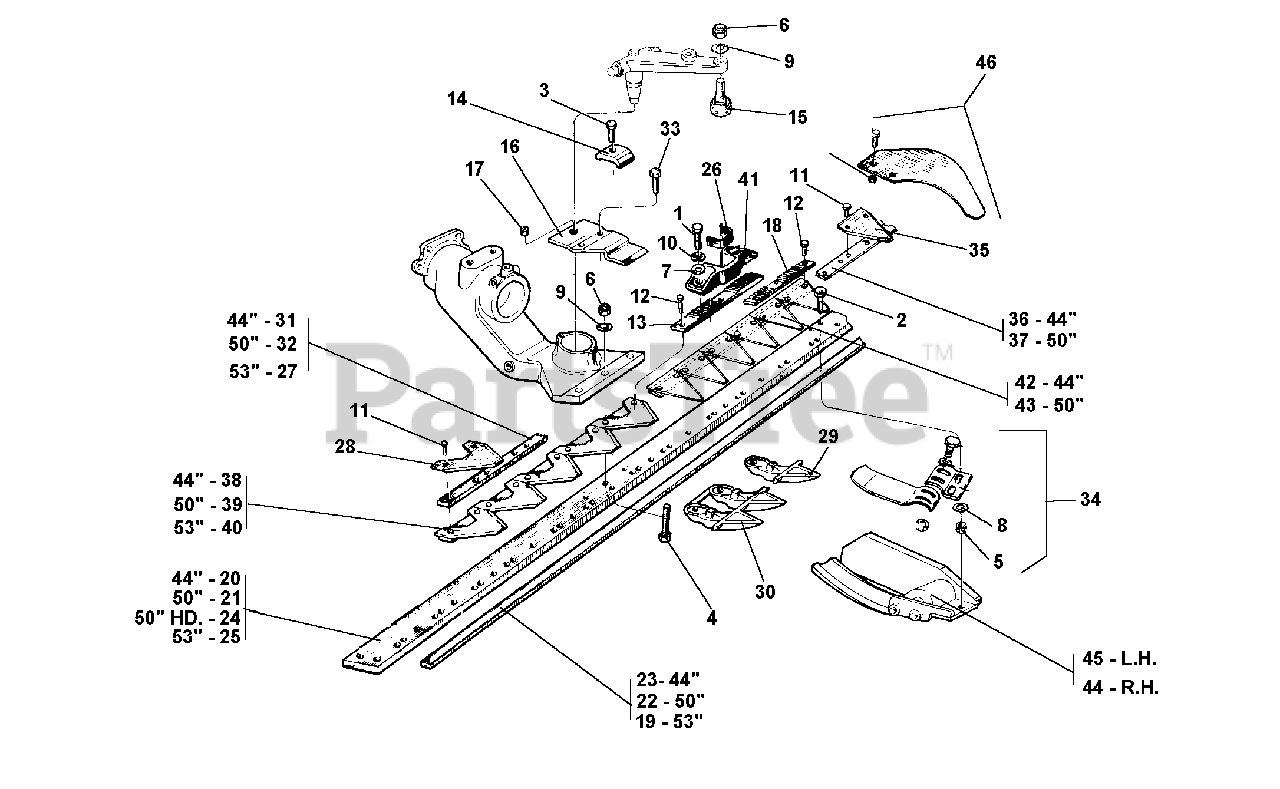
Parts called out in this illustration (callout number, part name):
1	SCREW M8 X 16
2	SCREW M8 X 25
3	SCREW TE M10 X 35 UNI 5739-8G
6	SELF LOCKING NUT
7	WASHER, FLAT 8.4
8	SUPER WASHER 8 DIN 6796
9	SUPER WASHER 10 DIN 6796
10	WASHER, LOCK 8.4
11	RIVET 5.3 X 14
12	RIVET TSV 5.3 X 14
13	SUPPORT, BLADE CONNECTION
14	HOLDER, STRIP
15	BLADE CONTROL PIN
16	HOLDER, BLADE, MULCHING
17	SCREW, HEADLESS M16 X 12
18	BLADE PLATE
19	19 SECTIONS BLADE GUIDE
20	BAR, CENTRAL, 1.10
21	BAR, CENTRAL, 1.27
22	GUIDE, BLADE L 1270
23	GUIDE, BLADE, 15 SECTIONS
24	HEAVY FRONT BAR 1.27 MT.
25	FRONT BAR 1.40 MT.
27	STRIP, FOR 19-SECTION BLADE
28	SECTION, SCORED BLADE
29	FINGER, SINGLE
30	TOOTH, DOUBLE MULCHING
31	STRIP, 15 SEC. BLADE
32	STRIP, 17 SEC. BLADE
33	SPECIAL SCREW
34	SLEDGE ASSEMBLY
35	INDIVIDUAL BLADE, NA
36	STRIP WITH 22 SECTIONS
37	STRIP WITH 25 SECTIONS
38	BLADE, 15 SECTIONS
39	BLADE, 17 SECTIONS
40	BLADE 19 SECTIONS
41	BLADE CONNECTION
42	BLADE WITH 22 NARROW SECTIONS
43	BLADE WITH 25 NARROW SECTIONS
44	RIGHT SLEDGE
45	LEFT SLEDGE
46	CUTTER BAR SIDE PROTECTION
